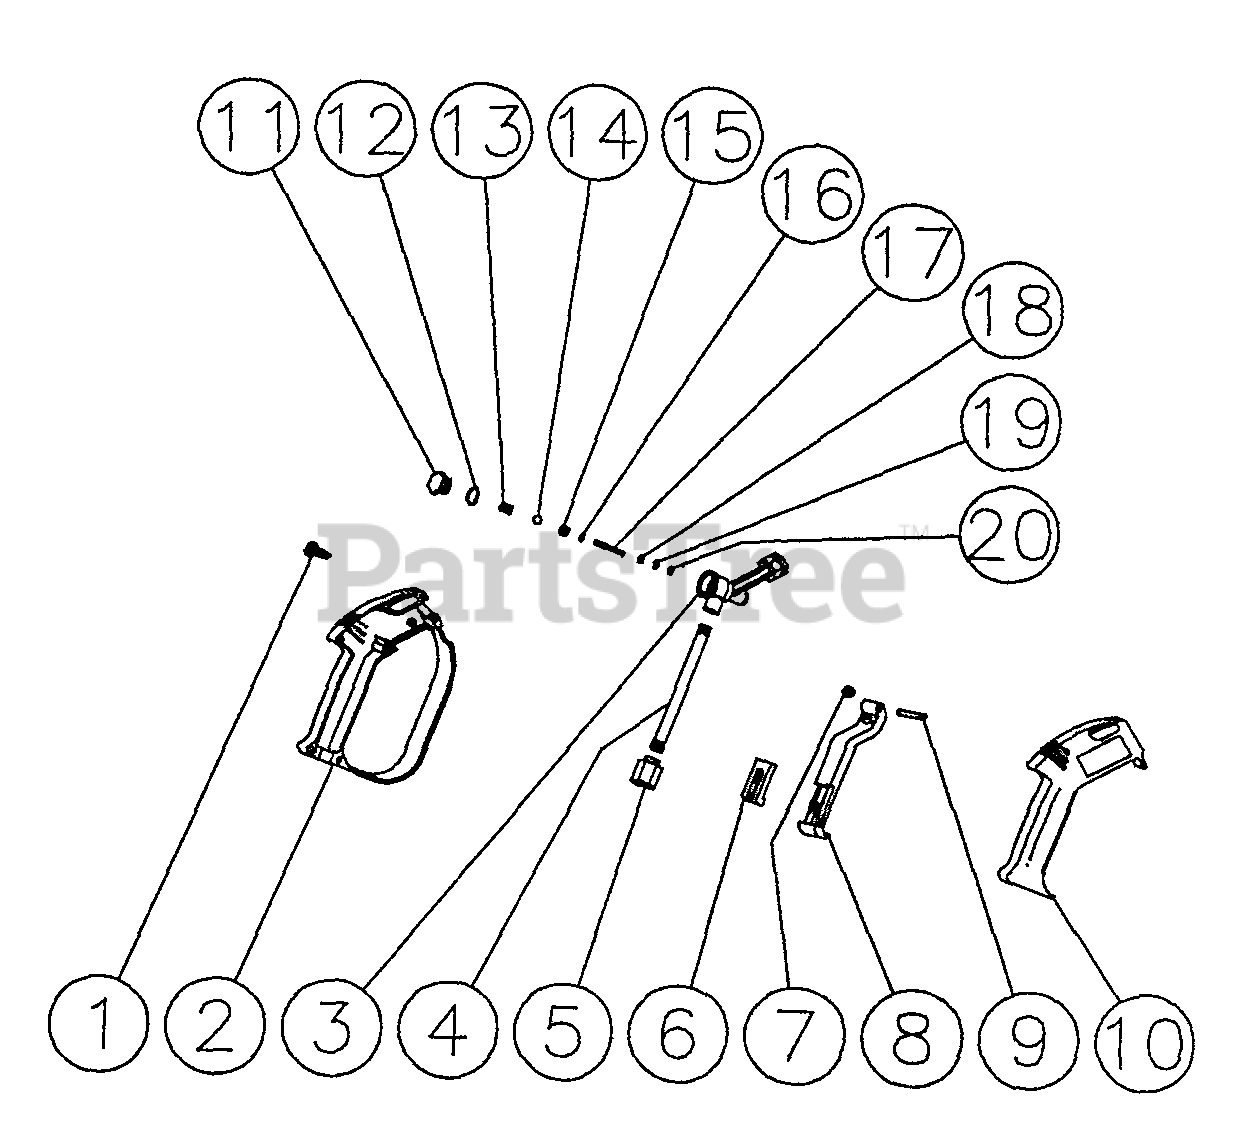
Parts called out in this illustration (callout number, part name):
2	Plastic Housing (Left Side)
6	Trigger Safety Lock
7	Trigger Rest
9	Trigger Pin
10	Plastic Housing (Right Side)
11	Plug
12	O-ring
13	Spring
14	Ball
15	Seat
16	O-ring
17	Pin
18	Washer
19	O-ring
20	Back-up Ring
